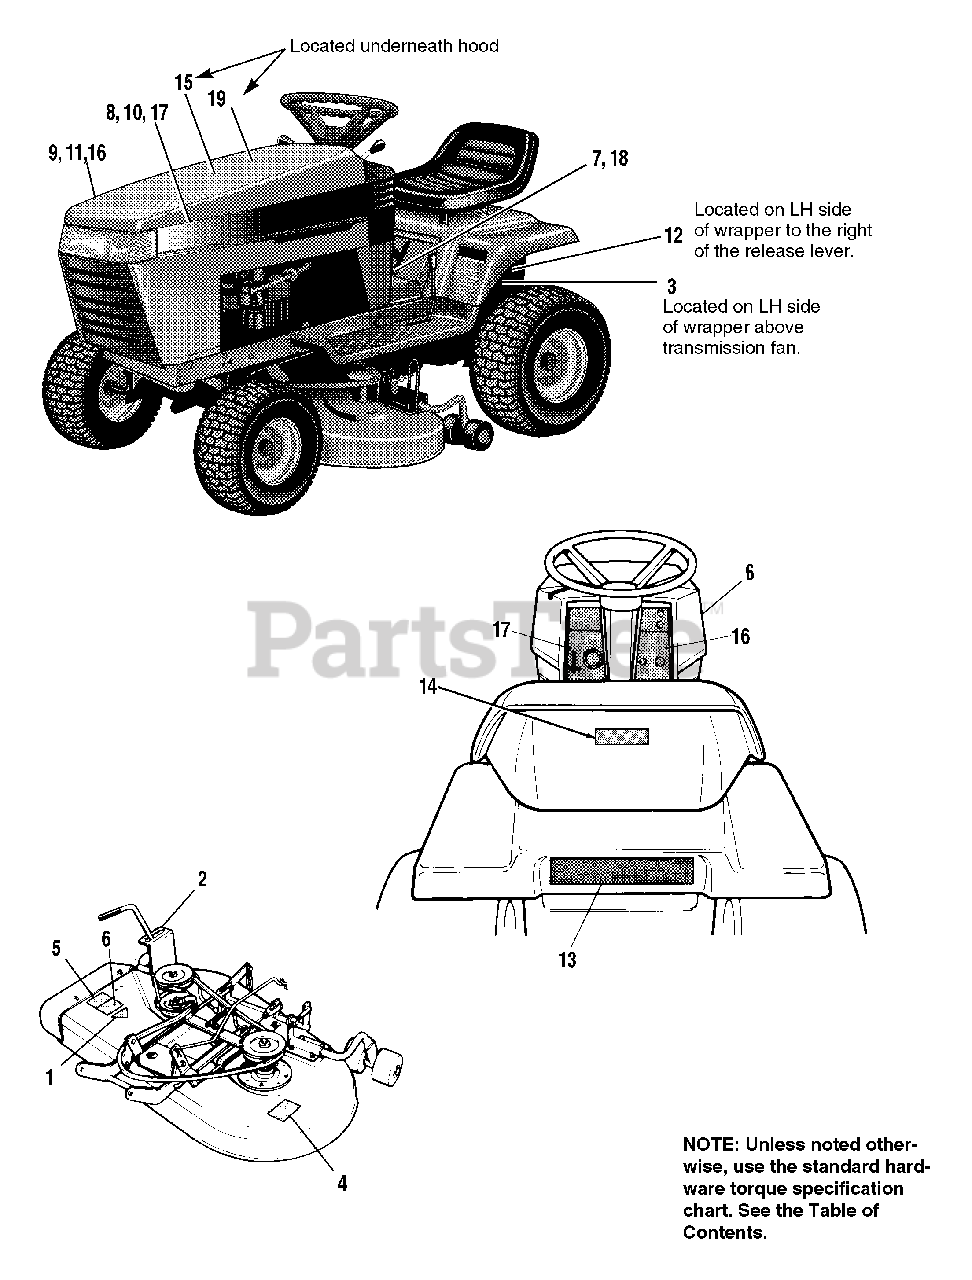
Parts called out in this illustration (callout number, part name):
1	DECAL, OPEI
2	DECAL, Mower Height
3	DECAL, Warning, Fan,
4	DECAL, Danger, Rotating Blade
5	DECAL, Danger, Deflector in Place
6	DECAL, Cutting Width, 36"
7	DECAL, Shift Pattern
8	DECAL, Hood, 512H AGCO ALLIS, LH
9	DECAL, Hood, 512H AGCO ALLIS, RH
10	DECAL, Hood, 512G AGCO ALLIS, LH
11	DECAL, Hood, 512G AGCO ALLIS, RH
12	DECAL, Release Valve
13	DECAL, AGCO Allis
14	DECAL, USA
15	DECAL, Touch-up Paint
16	DECAL, Dash, RH
17	DECAL, Dash, LH
18	DECAL, Shift Pattern
19	DECAL, Drive Belt
